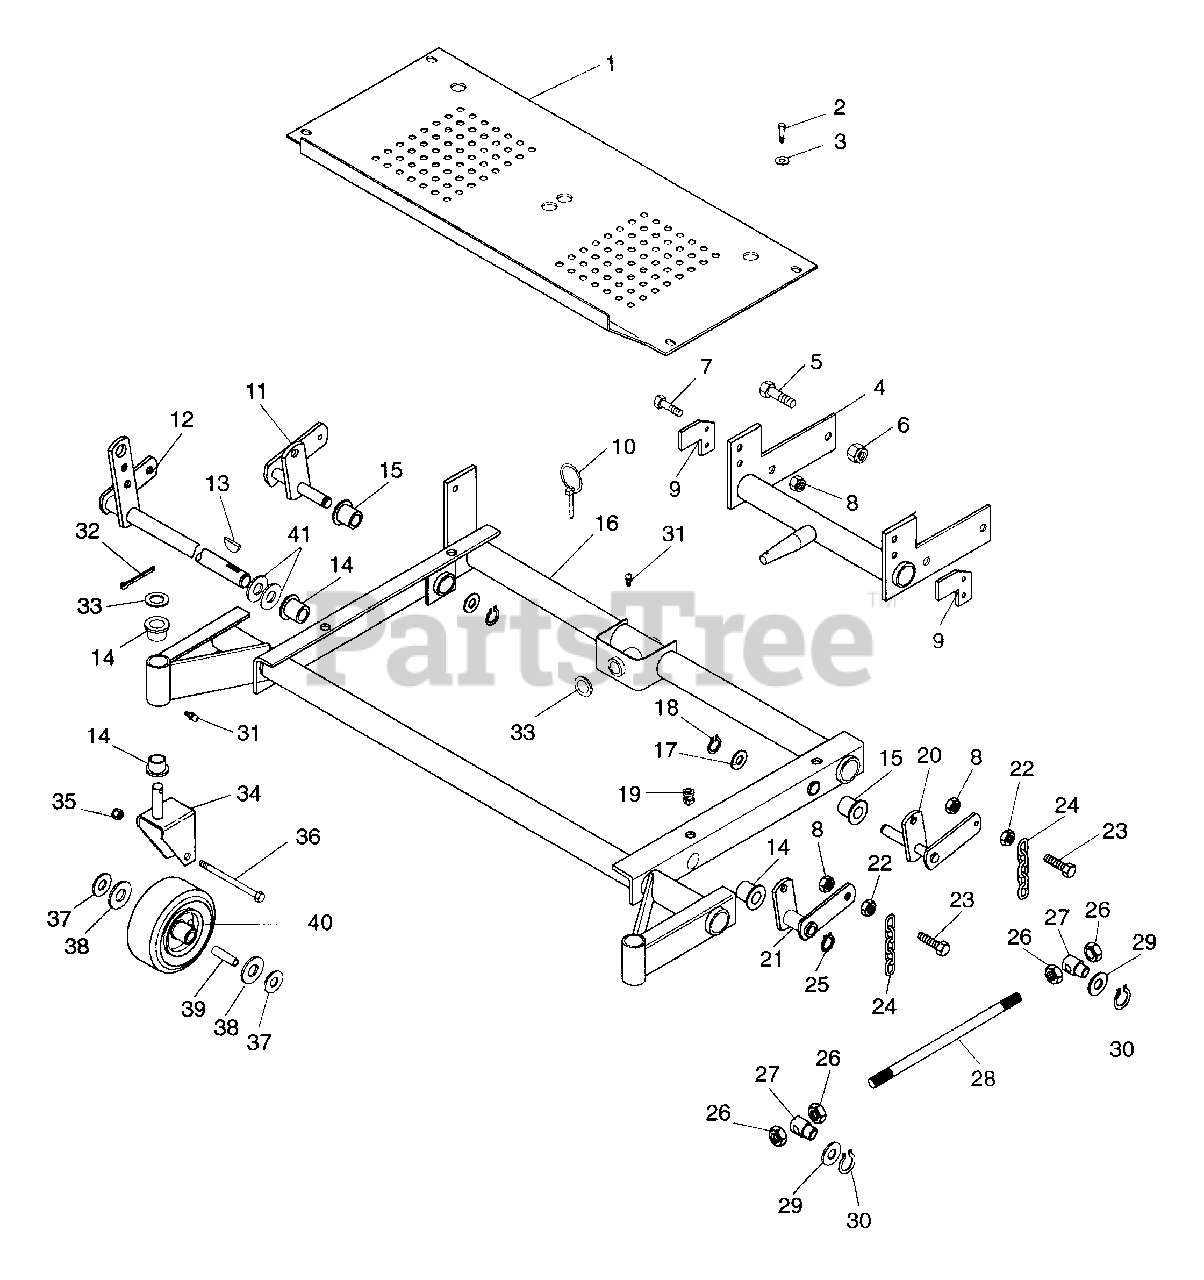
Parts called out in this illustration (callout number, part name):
1	Footboard PM200
2	Screw-Machine .25-20
3	Washer-Flat-Steel .281 x .625 x .065
4	Weldment, Mower Frame Mounting
5	Bolt-Hex .625-11 x 1.50
6	Nut-Locking-Nylon .625-11
7	Bolt-Hex .38-16 x 1.125
8	Nut-Locking-Nylon .375-16 Grade 2
9	Plate, Pivot Stop
10	Pin-klik .25 x 1.75
11	Weldment, Lift Arm Shaft
12	Weldment, Mower Lift Shaft
13	Key-Woodruff .25 x 1.0
14	Bushing-Flange 1.020 x 1.385 x .75 x 1.75
15	Bushing-Flange .762 x 1.0 x .580 x 1.48
16	Weldment, Front Frame PM200
17	Bearing-N-Thrust .752 x 1.24 x .031
18	Ring-Retaining-External .689 x .077
19	Clip, U-Type
20	Weldment, Lift Arm Shaft (R.H.)
21	Weldment, Lift Arm
22	Nut-Hex .375-16 Grade 2
23	Bolt-Hex .38-16 x 1.50 Grade 5
24	Chain, Link
25	Ring-Retaining-External 1.00 x .078
26	Nut .50-13
27	Pivot, Mower Lift
28	Tie Rod, Lift Lever
29	Washer-Flat-Steel .630 x 1.005 x .062
30	Ring-Retaining-External .625 x .050
31	Fitting-Lube .25-28 x .256
32	Pin-Cotter .12 x 1.25
33	Bearing-R-Thrust 1.022 x 1.552 x .030
34	Weldment, Caster Fork
35	Nut-Locking-Nylon .50-13 Grade 2
36	Bolt-Hex .500-13 x 8.00
37	Washer-Flat-Steel .531 x 1.250 x .100
38	Washer-Flat-Steel .813 x 1.370 x .100
39	Axle, Caster
40	Tire/Wheel Assembly 13 x 5-6
41	Washer-Flat-Steel .063 x 2.000 x .134
41	Tire, 13 x 5-6 Turf Trac
